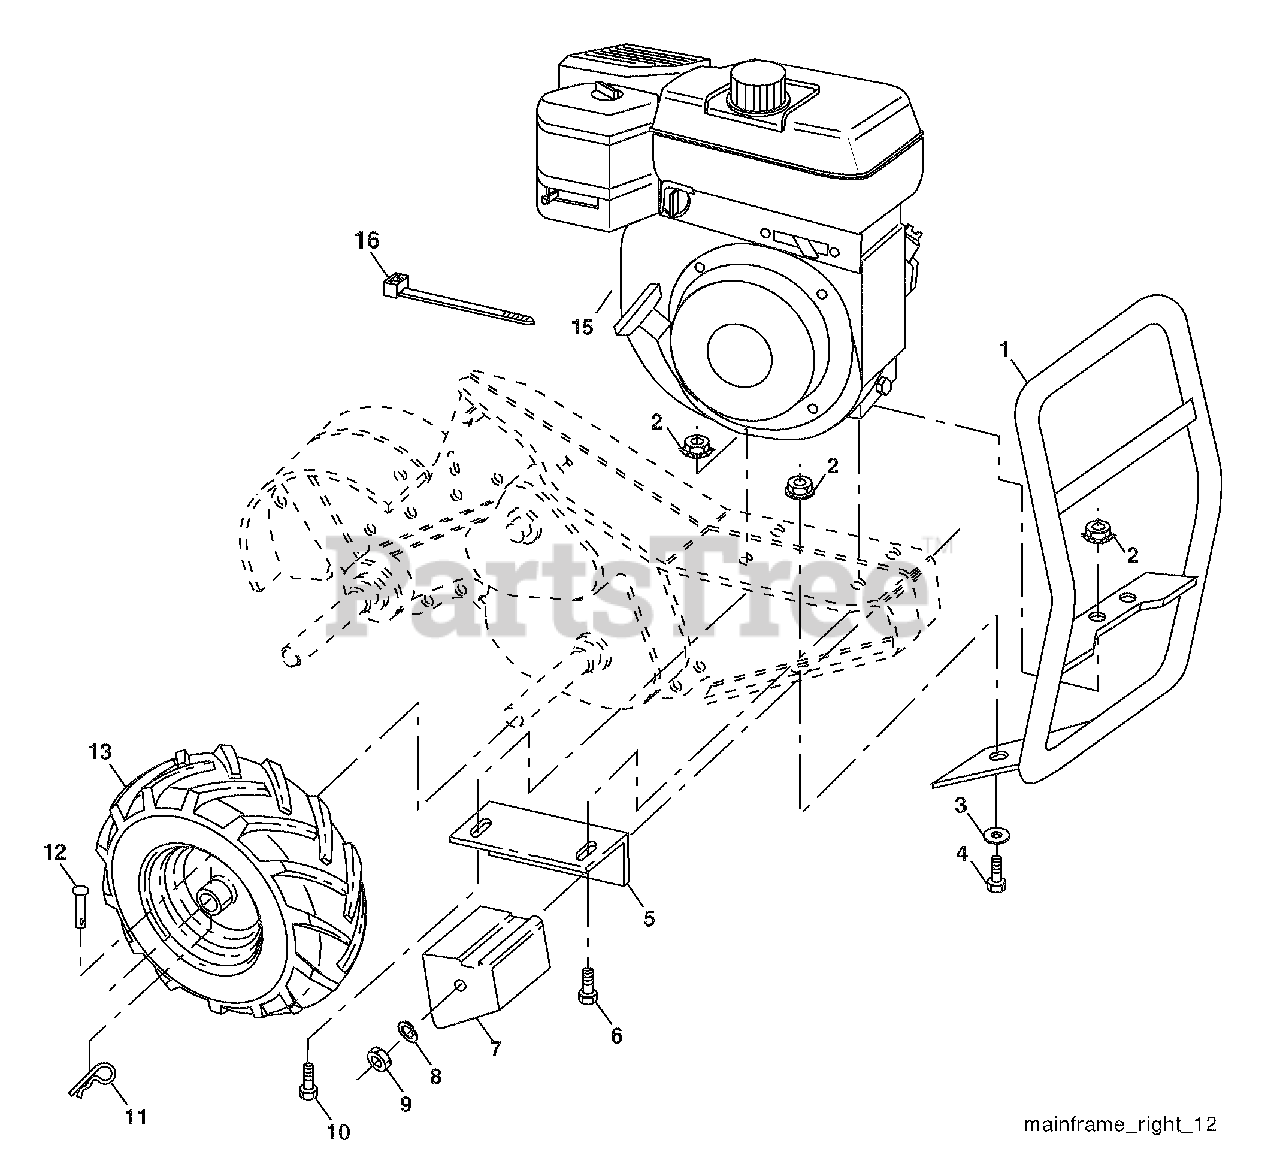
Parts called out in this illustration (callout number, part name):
1	Bumper Asm.
2	Locknut, Hex, Flange 5/16-18
3	Washer 11/32 x 11/16 x 16 Ga.
4	Bolt 5/16-18 x 3/4
5	Bracket, Reinforcement
7	Counter Weight, R.H.
8	Washer, Lock 3/8
9	Nut, Hex 3/8-16
10	Bolt, Hex 5/16-18 x 1-1/2
11	Clip, Hairpin
12	Rivet, Drilled
13	Tire Valve
16	Tie, Cable
22	Bolt 5/16-18 x 1-3/4
